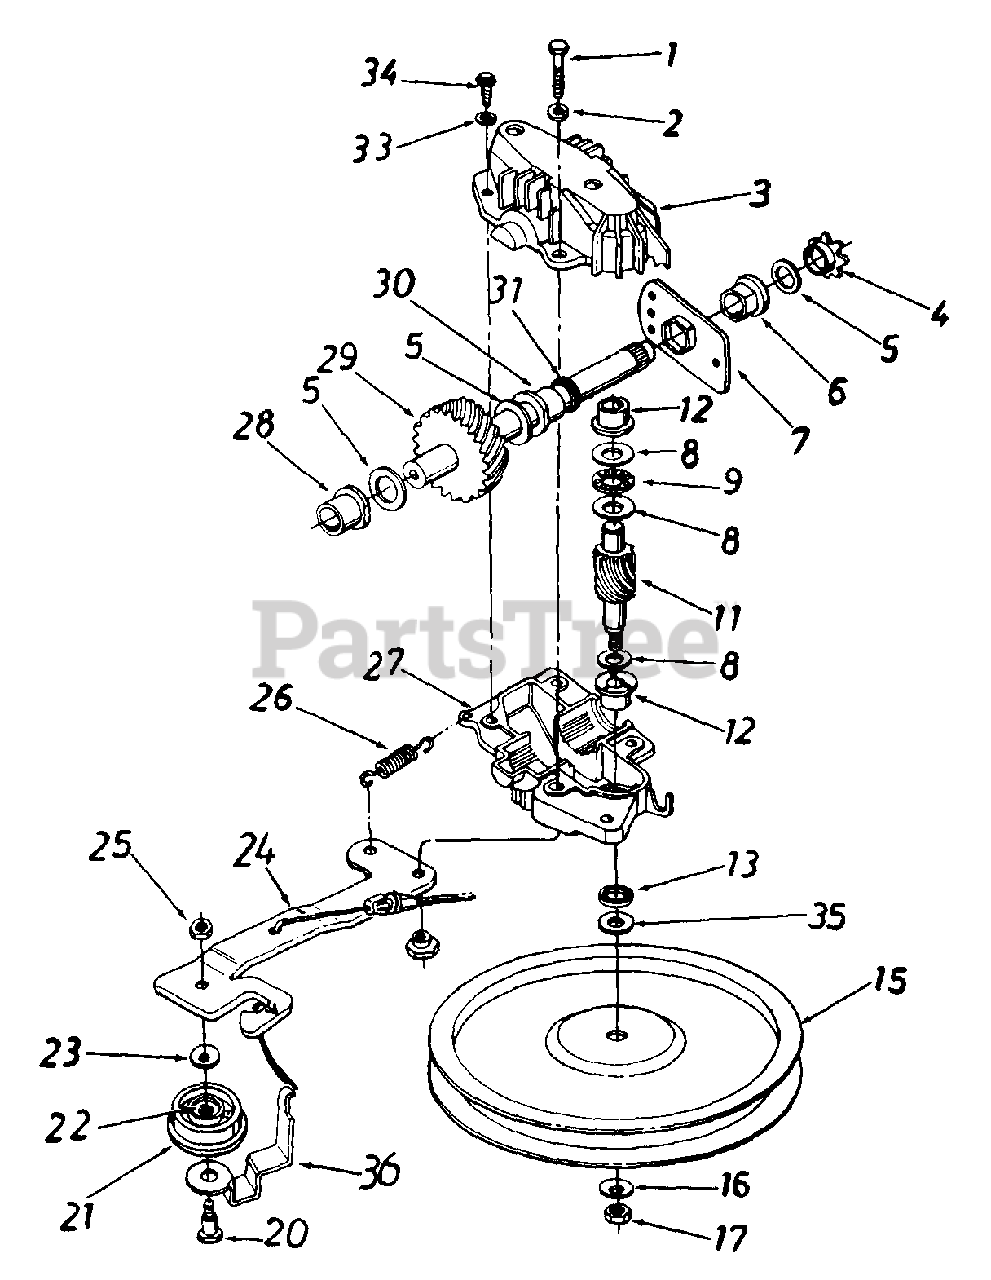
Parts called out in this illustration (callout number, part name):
1	Hex Bolt 1/4 - 20 x 1.25" Lg. w/Patch
2	L-Wash. 1/4" I.D.
3	Upper Hsg. Half
4	#48 Sprocket 7 Tooth x 1/2 Pitch
5	Fl-Wash. 5/8" I.D. x .030
6	Hex Flange Brg. .631" I.D.
8	Thrust Wash. .382" I.D. x .70" O.D.
9	Thrust Bearing .375" I.D. x .812" O.D.
11	11 Tooth Pinion Shaft
12	Flange Bearing
13	Oil Seal
15	Fl-Pulley 5.06" O.D.
16	Bell-Wash. .265" I.D. x .75"
17	Hex L-Nut 1/4-28 L.H. Thd.
20	Shld. Bolt .375" Dia. x .40"
21	Fl-Idler Plastic 1.50" Dia.
22	Needle Brg. .375" x .31
23	Bell-Wash. .265" I.D. x .75"
24	Idler Brk't. Ass'y.
25	Hex Patch L-Nut 1/4 - 28 Thd.
26	Extension Spring 1.12" Lg.
27	Lower Hsg. Half
28	Flange Bearing .566 Dia.
29	Shaft Ass'y.
30	Flange Bearing .629 Dia.
31	Oil Seal .625 Dia.
33	L-Wash. #10 I.D.
34	Hex B-Tap Scr. #10 x .62"
35	Hex Washer .26" x .88"
36	Belt Keeper
